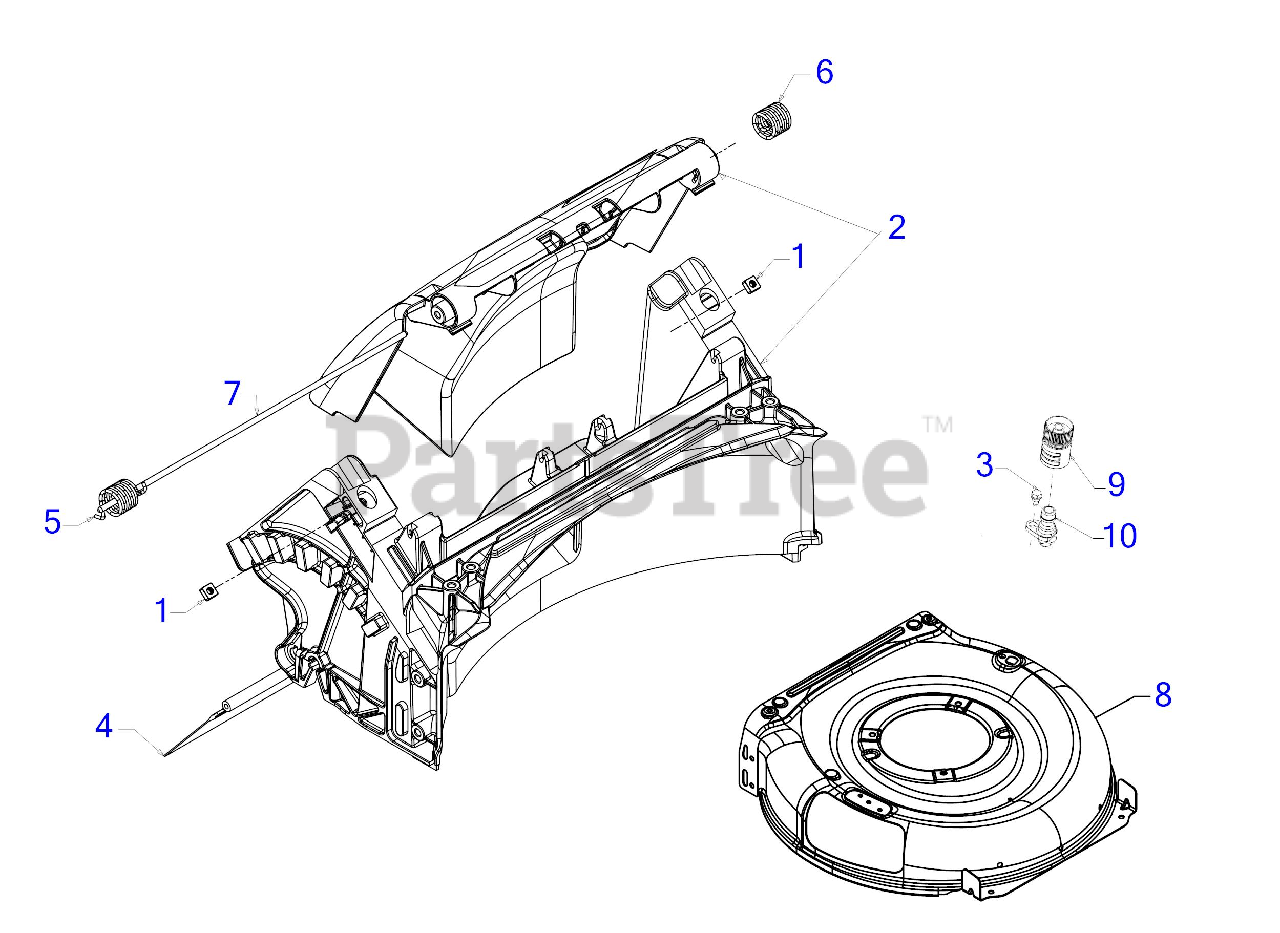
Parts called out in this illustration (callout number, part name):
1	SQUARE NUT 1/4-20
2	REAR BAG DOOR ASSEMBLY
3	SHOULDER SCREW 1/4-20 x .50
4	TRAILSHIELD
5	TORSION SPRING (RH)
6	TORSION SPRING (LH)
7	REAR DOOR PIVOT ROD
8	21" DECK (3N1)
9	WATER NOZZLE
10	DECK WASH NOZZLE
